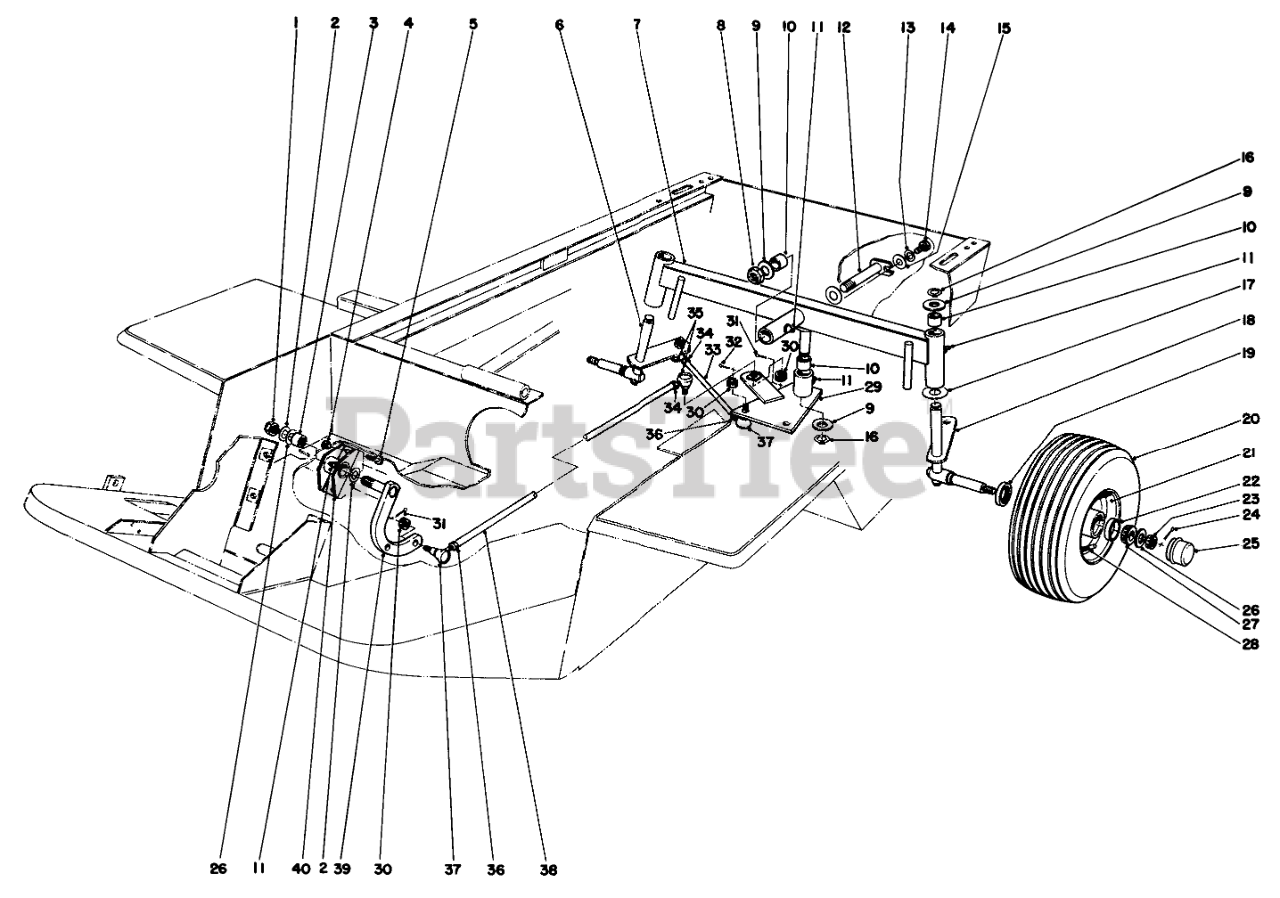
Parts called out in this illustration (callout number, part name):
1	NUT-LOCK, NI
2	THRUST WASHER
3	BEARING-NEEDLE
4	NUT-LOCK, NI
5	SCREW-HH
6	Spindle R.H.
7	Rear Axle (Incl. Ref. #10 & 11)
8	NUT-LOCK, NI
9	WASHER-THRUST
10	BUSHING
11	FITTING-GREASE
12	Pin-RearAxle
13	WASHER-LOCK
14	SCREW-HH
15	WASHER-FLAT
16	RING-RETAINING
17	WASHER-THRUST
18	Spindle L.H.
20	TIRE 4 PLY
21	Rim (Incl. Ref. #22)
22	BEARING-CUP, TAPERED
23	NUT-HEX, SLOTTED
24	PIN-COTTER
25	CAP-DUST
26	WASHER-FLAT
27	BEARING-CONE, TAPERED
28	VALVE STEM AND CAP ASM
29	Steering Plate (Incl. Ref. #10 & 11)
30	NUT-SLOTTED
31	PIN-COTTER
32	PIN-COTTER
33	STRG TIE ROD R
34	NUT-HJ (LH THREAD)
35	Socket Assembly L.H. (Incl. Ref. #30)
36	NUT-JAM
37	Socket Assembly R.H. (Incl. Ref. #30)
38	REAR STRG TUBE PP
39	PIVOT ARM WA
40	Pivot Mount (Incl. Ref. #3 & 11)
